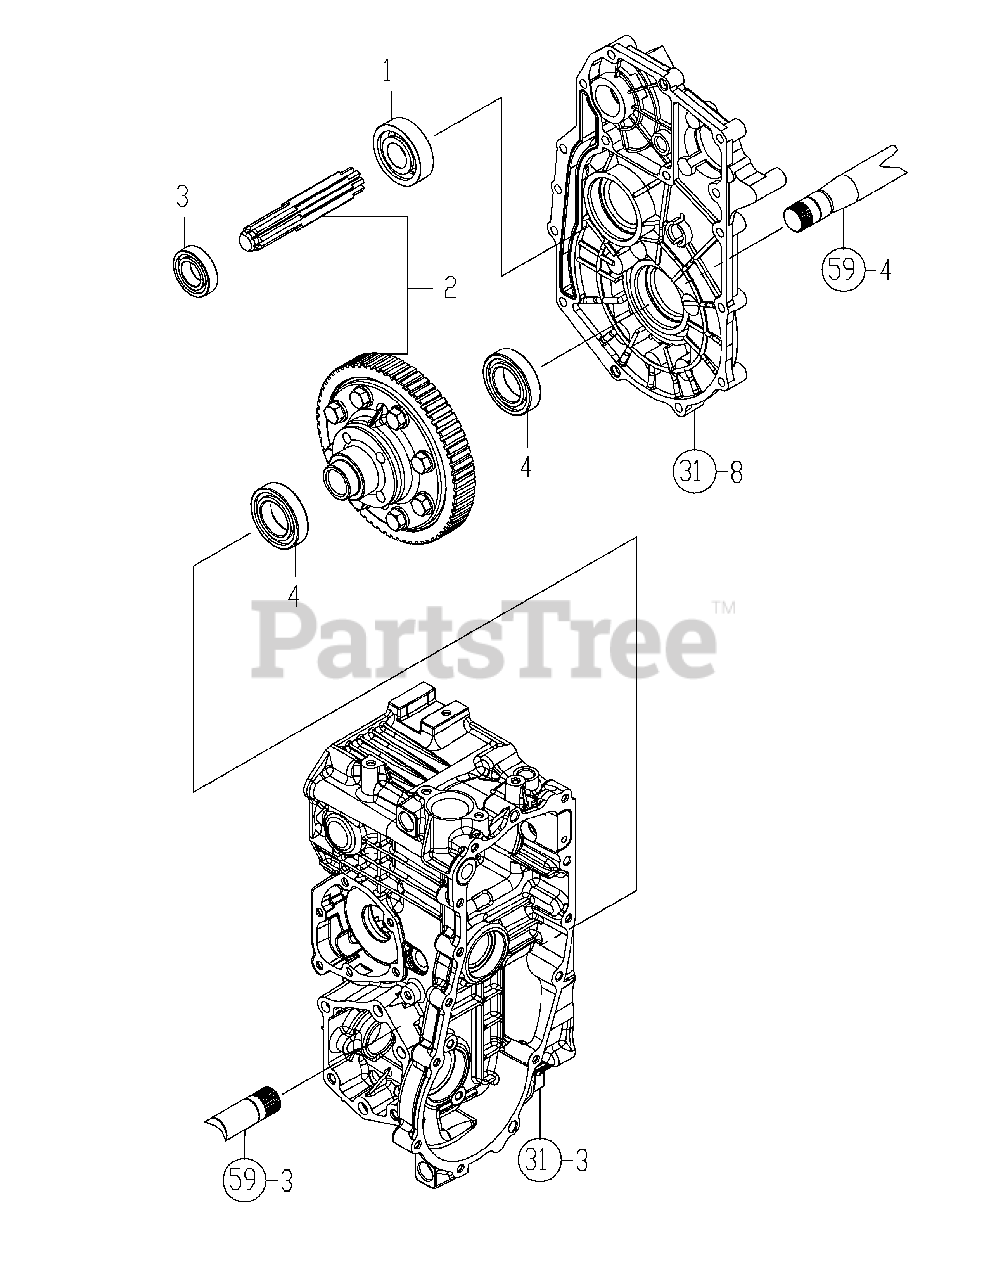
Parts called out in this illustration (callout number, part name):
1	BEARING, TMB305
2	GEAR KIT, FINAL
3	BEARING, 6005SH2
4	BEARING, 6007 NTN
